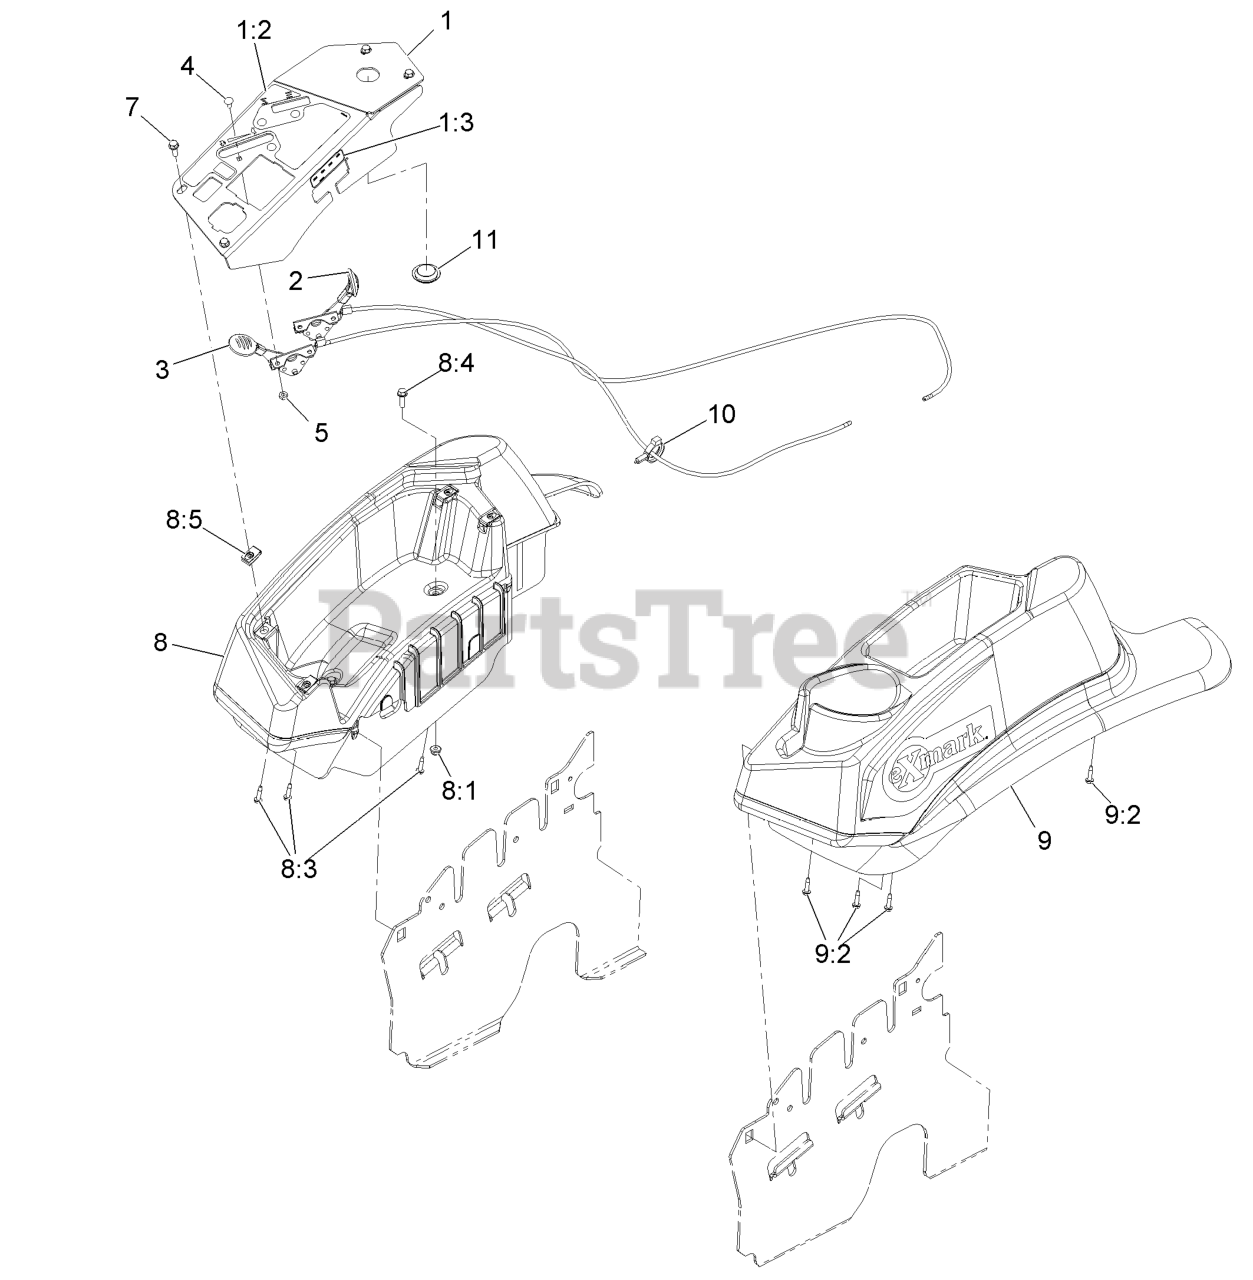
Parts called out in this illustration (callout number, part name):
1	CONSOLE,PANEL W/DECAL
1:2	DECAL-CONTROL PANEL
1:3	DECAL-FUSE
2	ASM, CHOKE CABLE
3	ASM,THROTTLE CABLE
4	BOLT-CARR
5	NUT-LOCK, NI
7	SCREW-HWH
8	CONSOLE,RH NARROW ASM
8:3	SCREW,THD FORM,HWH
8:4	SCREW-HWH
8:5	Nut-Retainer-Panel 1/4-20
9	CONSOLE.LH NARROW ASM
9:2	SCREW,THD FORM,HWH
10	CLAMP-HOSE
11	PLUG-PLASTIC
